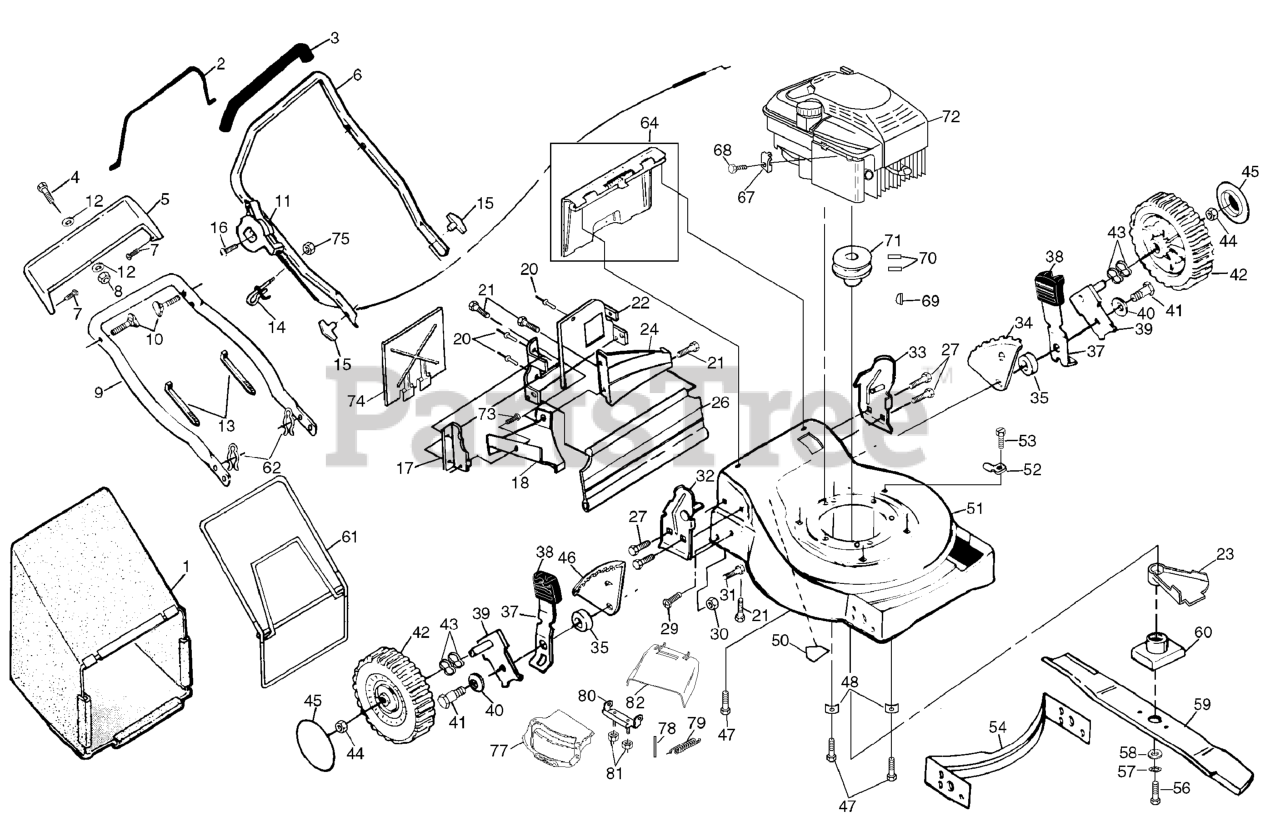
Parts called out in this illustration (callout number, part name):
1	GRASS BAG
2	CONTROL BAR
3	HANDLE GRIP
4	SCREW
5	TRIM PLATE
6	HANDLE, UPPER
8	NUT
9	HANDLE, LOWER PM
10	HANDLE BOLT
11	THROTTLE CONTROL
13	TIE GUIDE
14	ROPE GUIDE
15	HANDLE KNOB
16	SCREW 1/4-20X1.75
17	SIDE BAFFLE
18	DISCHARGE BAFFLE
20	RIVET BLIND
22	BACK PLATE
23	DEBRIS SHIELD
24	REAR BAFFLE
26	REAR SKIRT
27	SELF-TAPPING SCREW 5/16-18X3/4
29	HINGE SCREW
30	LOCKNUT PM
32	HANDLE BRACKET RH
33	HANDLE BRACKET LH
34	WHEEL ADJ BRKT RF-LR
35	RP SPACER HT ADJ
37	SELECTOR SPRING
38	SELECTOR KNOB
39	AXLE ARM
40	WASHER.BELLEVILLE (3 2 LB)
41	BOLT
42	WHL & TIRE ASSEMBLY
43	WAVE WASHER
44	HEX FLANGE LOCKNT
46	WHEEL ADJ BRKT RR-LF
47	BOLT 3/8-16X1-1/8
48	WASHER.ENGINE.BZP
50	DECAL HYT
51	HOUSING KIT, LAWNMOWER
52	GUIDE CLIP PM
53	TAPPING SCREW
54	FRONT BAFFLE
56	SCREW, HEX HD 3/8-24 X 1-3/8
57	LOCKWASHER
58	WASHER,HARDEN
60	BLADE ADAPTOR
61	CATCHER.FRAME.WALK
62	HAIRPIN COTTER
64	REAR DOOR ASSEMBLY
67	WASHER
68	SCREW.HEX.HEAD.WASHER.10-16
69	HI PRO KEY PM WSL
71	ENGINE.PULLEY.FWG
73	SCREW.HXTAP.10-24
74	MULCHER PLATE
75	NUT
77	COMBI-CUT DOOR
78	ROD.HINGE.COMBI-C
79	HINGE SPRING
80	BRACKET.HINGE ASM.W/FIN
81	NUT
82	CLIP-ON DISCHARGE
